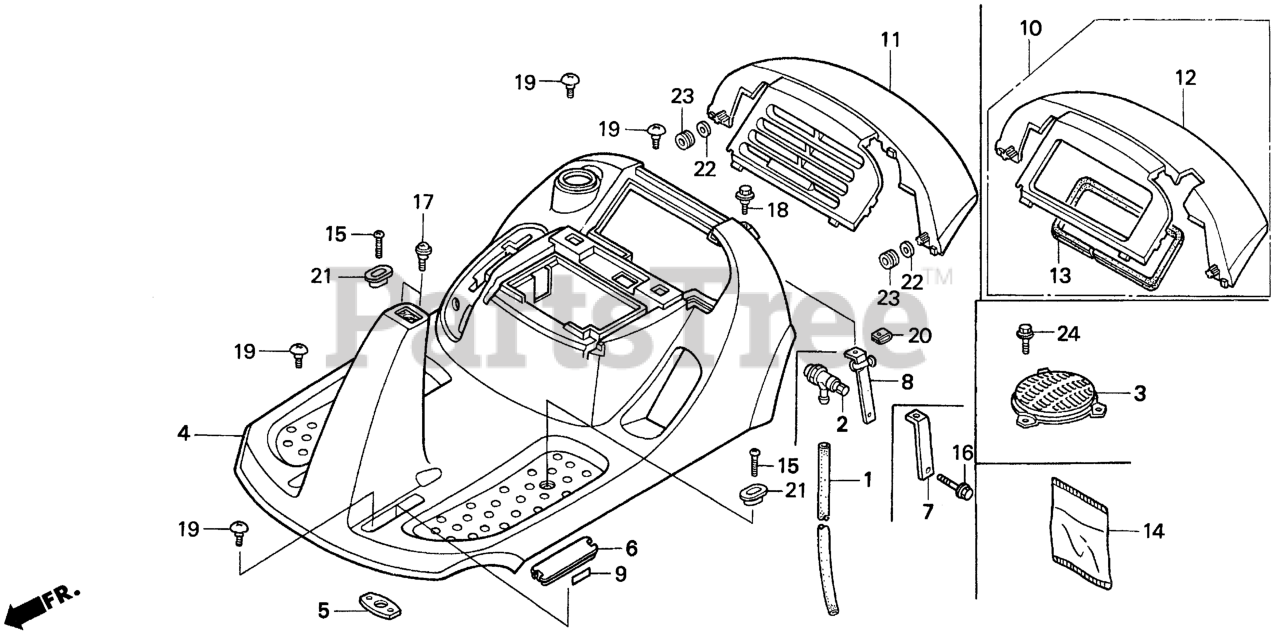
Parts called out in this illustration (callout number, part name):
1	TUBE, OIL DRAIN
2	VALVE, OIL SHUT-OFF
4	PLATFORM *R165* (JOLLY RED)
5	PLATE, STEERING SHAFT
8	BRACKET, PLATFORM
10	HOOD, RR. *R165* (JOLLY RED)
12	HOOD, RR. *R165* (JOLLY RED)
13	TRIM, RR. HOOD (N/A: SEE ASSEMBLY)
14	BAG, OWNER'S MANUAL
15	SCREW, TORUS (6X20)
17	SCREW, HANDLE COVER SETTING
18	BOLT, FLANGE (6MM)
19	SCREW, METER VISOR SETTING
20	NUT, CLIP (6MM)
21	WASHER (6X9)
22	WASHER (16MM)
23	GROMMET, RR. HOOD
NI	FLOOR MAT SET (NOT AVAILABLE)
